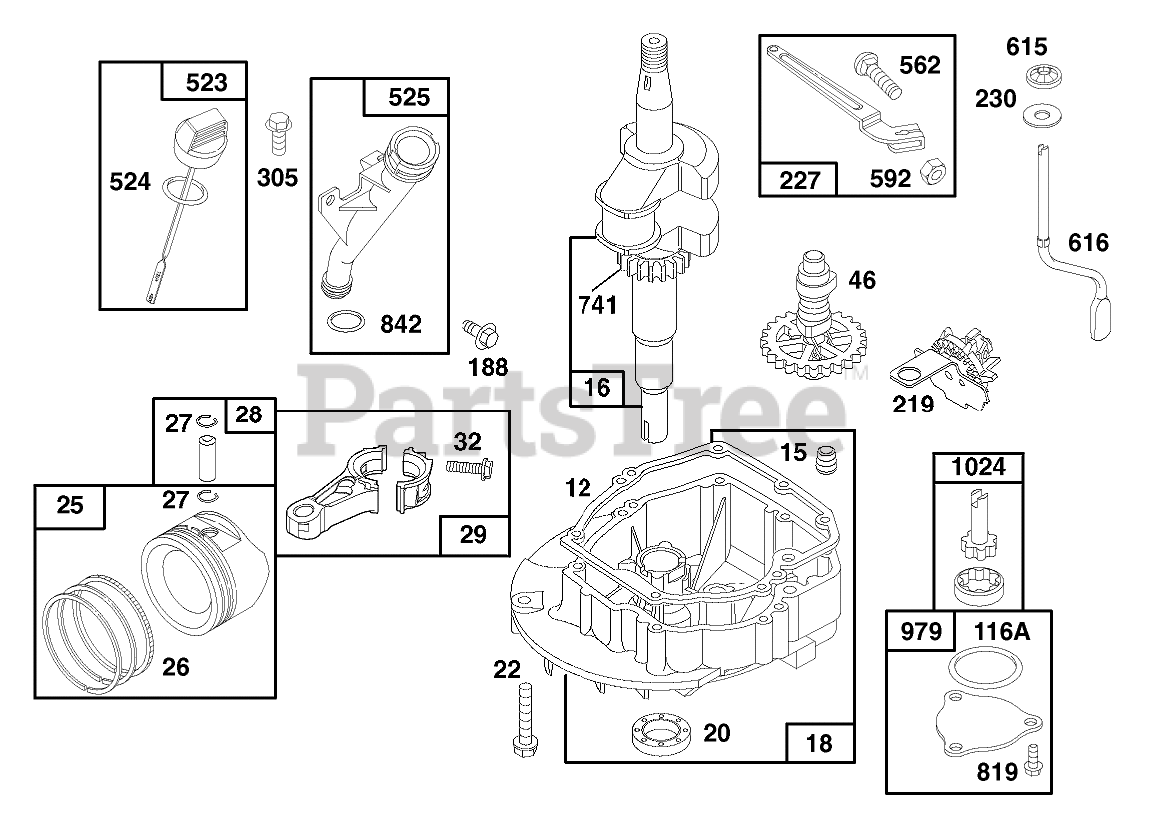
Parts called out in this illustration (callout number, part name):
12	ENGINE BASE GASKET
15	PIPE PLUG
16	CRANKSHAFT
18	ENGINE SUMP
20	SEAL-OIL
22	SCREW - ENGINE BASE
25	STD PISTON ASSEMBLY
26	STD RING SET
27	PISTON PIN LOCK
28	PIN ASM - PISTON
29	CONNECTING ROD
32	Connecting Rod
37	GUARD - FLYWHEEL
46	CAM GEAR
116A	O RING SEAL
188	Screw-Cap
219	GOVERNOR/OIL SLINGER
227	GOVERNOR LEVER ASSEMBLY
230	WASHER
305	SCREW - HEX HEAD
523	DIPSTICK-OIL
524	O-RING
525	OIL FILLER TUBE
562	GOVERNOR LEVER BOLT
592	HEX NUT
615	FASTENER
616	GOVERNOR CRANK
741	TIMING GEAR
819	SCREW - SEM
842	O-RING
979	OIL PUMP COVER
1024	OIL PUMP
